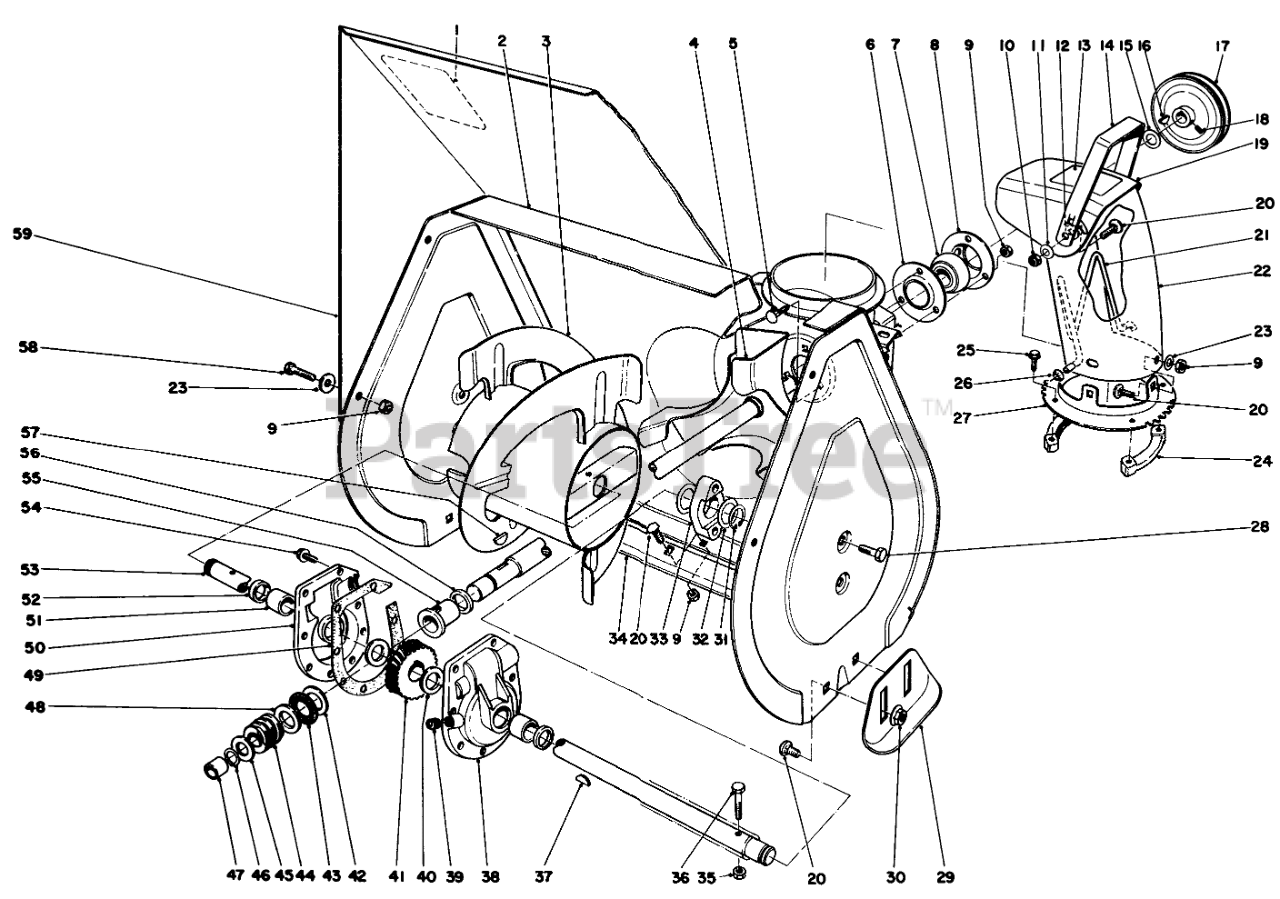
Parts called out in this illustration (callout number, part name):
5	BOLT-CARR
6	FLANGE-CUP, BEARING
8	FLANGE-CUP, BEARING
9	NUT-LOCK, NI
10	NUT-LOCK, CONE
11	WASHER-BELLEVILLE
12	WASHER-RUBBER
15	WASHER
16	KEY-WOODRUFF
17	PULLEY
18	SCREW-SET, SQH
20	BOLT-CARR
23	WASHER-PLAIN
24	RING-CHUTE, RETAINER
25	SCREW-SPECIAL
26	NUT-PUSH
28	SCREW-THD ROLL, HWH
30	NUT-HF
31	RING-RETAINING
32	WASHER
35	NUT-LOCK, CONE
36	SCREW-HH
37	KEY-WOODRUFF
39	PLUG-PIPE, SQH
40	WASHER-THRUST
42	WASHER-THRUST
43	BEARING-THRUST
45	WASHER-THRUST
46	RING-SNAP
47	BUSHING
48	WASHER-THRUST
49	GASKET-CASE, GEAR
51	BUSHING
52	SEAL-OIL
53	AUGER SHAFT
54	SCREW-TAPTITE
55	BUSHING-INPUT
56	RING-QUAD
57	KEY-WOODRUFF
58	SCREW-HH
